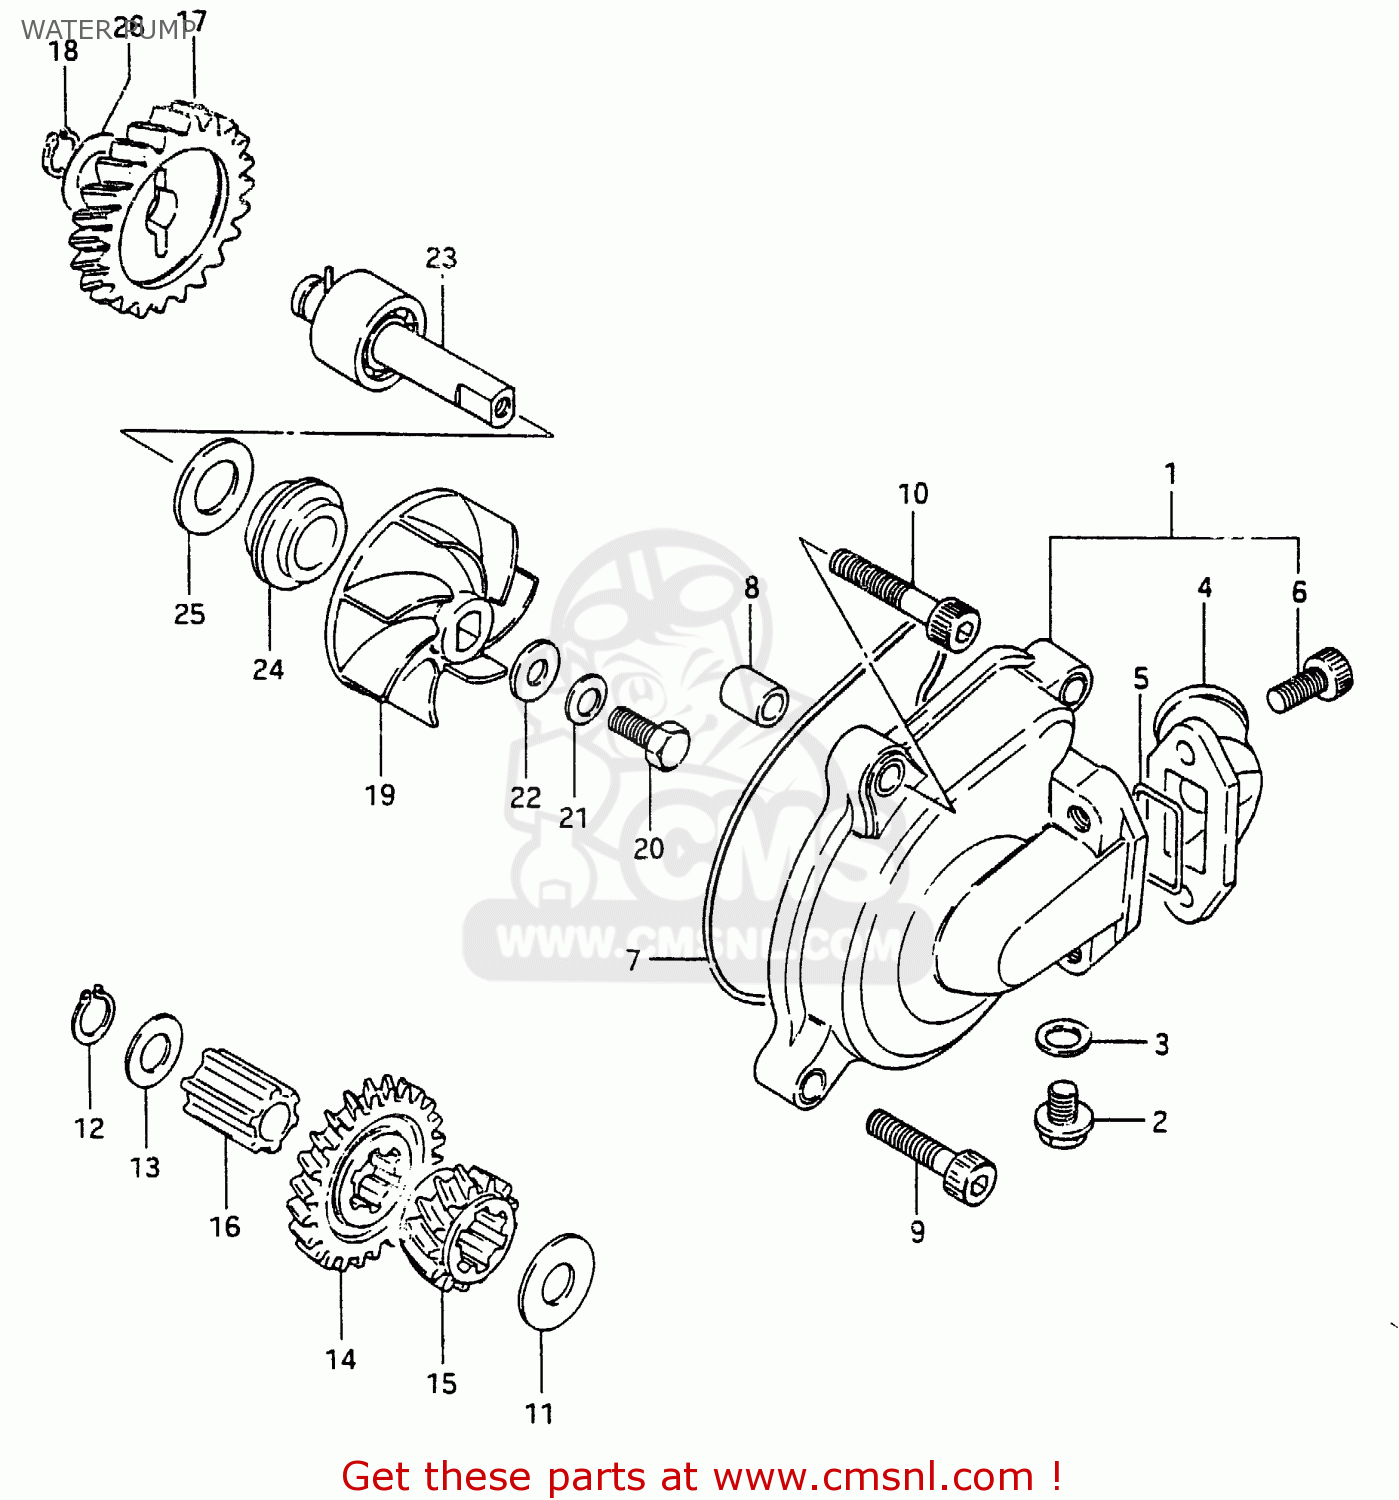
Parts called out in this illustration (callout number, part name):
1	CASE, WATER PUMP
2	BOLT,DRAIN
3	GASKET 8.2X14X1 (NAS)
4	CONNECTOR, INLET
5	O RING,WATER PUMP CONNECTOR
6	BOLT
7	O RING,WATER PUMP CASE
8	PIN
9	BOLT
10	BOLT
11	THRUST WASHER
12	CIRCLIP
13	SHIM
14	GEAR, WATER PUMP IDLER NO.1
15	GEAR, WATER PUMP IDLER NO.2
16	BUSH, WATER PUMP IDLER GEAR
17	GEAR, WATER PUMP DRIVEN
18	CIRCLIP
19	IMPELLER,WATER PUMP
20	BOLT(6X13)
21	WASHER
22	GASKET (NAS)
23	SHAFT,WATER PUMP
24	SEAL,WATER PUMP SHAFT
25	SEAL,OIL(10X20X5)
26	SHIM T:0.5
